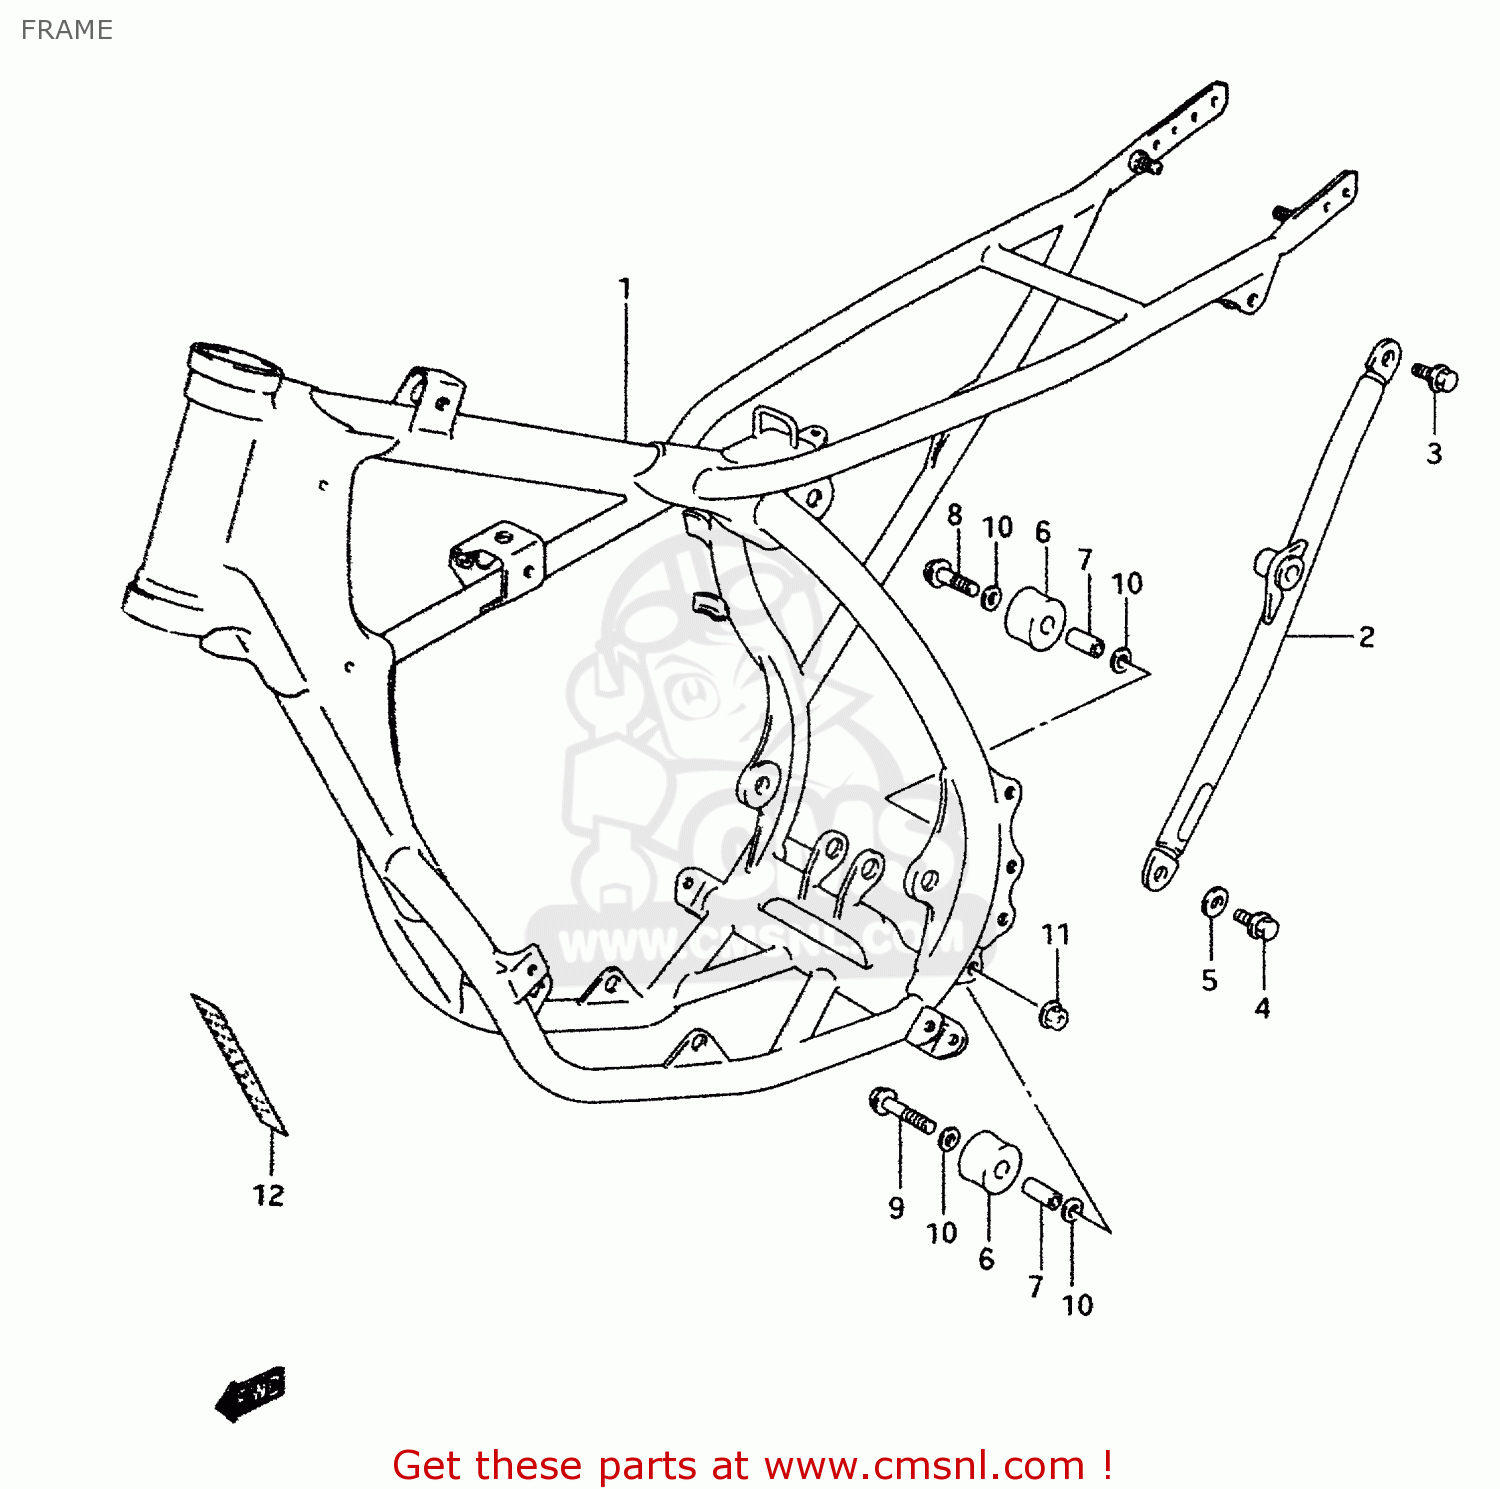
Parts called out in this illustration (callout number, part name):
1	FRAME
2	TUBE,FRAME SIDE(CHARCOAL)
3	BOLT(8X22)
4	BOLT(8X16)
5	WASHER
6	ROLLER,CHAIN CONTROL
7	SPACER(8.6X12X25.5)
8	BOLT(8X38)
9	BOLT
10	WASHER
11	NUT
12	PLATE,WARNING
